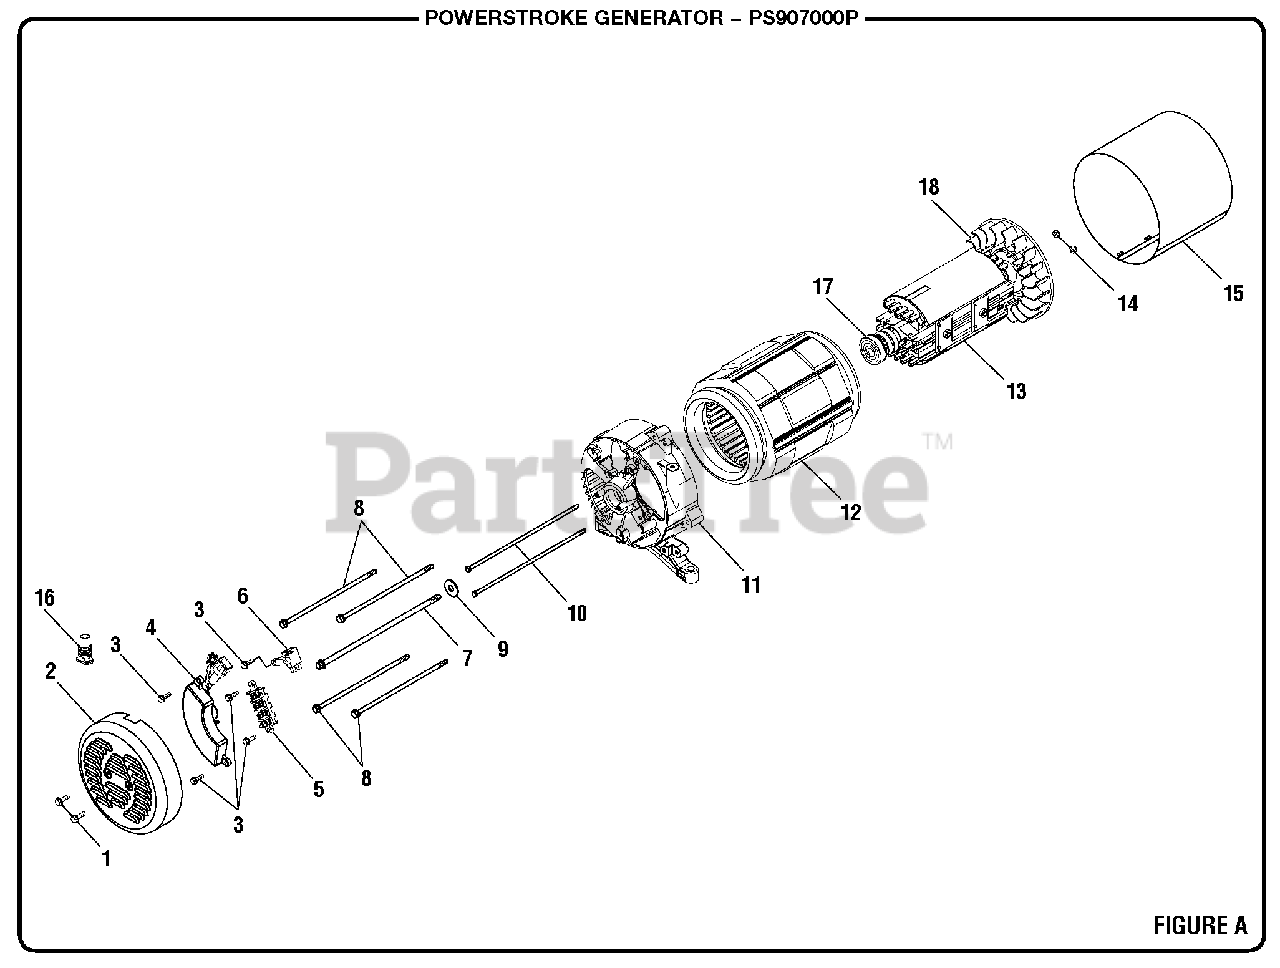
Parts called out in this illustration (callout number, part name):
1	Bolt (M5 x 12 mm, Hex Flange Hd.)
2	Brush Cover
3	Bolt (M5 x 16 mm, Hex Flange Hd.)
4	Automatic Voltage Regulator
5	Terminal Block
6	Brush Assembly
7	Rotor Bolt (170 mm)
8	Stator Bolt (170 mm)
9	Rotor Washer
10	Bolt (M5 x 170 mm, Hex Hd.)
11	Bearing Carrier
14	Hex Nut (M5)
15	Generator Head Cover
16	Rubber Boot
17	Ball Bearing
